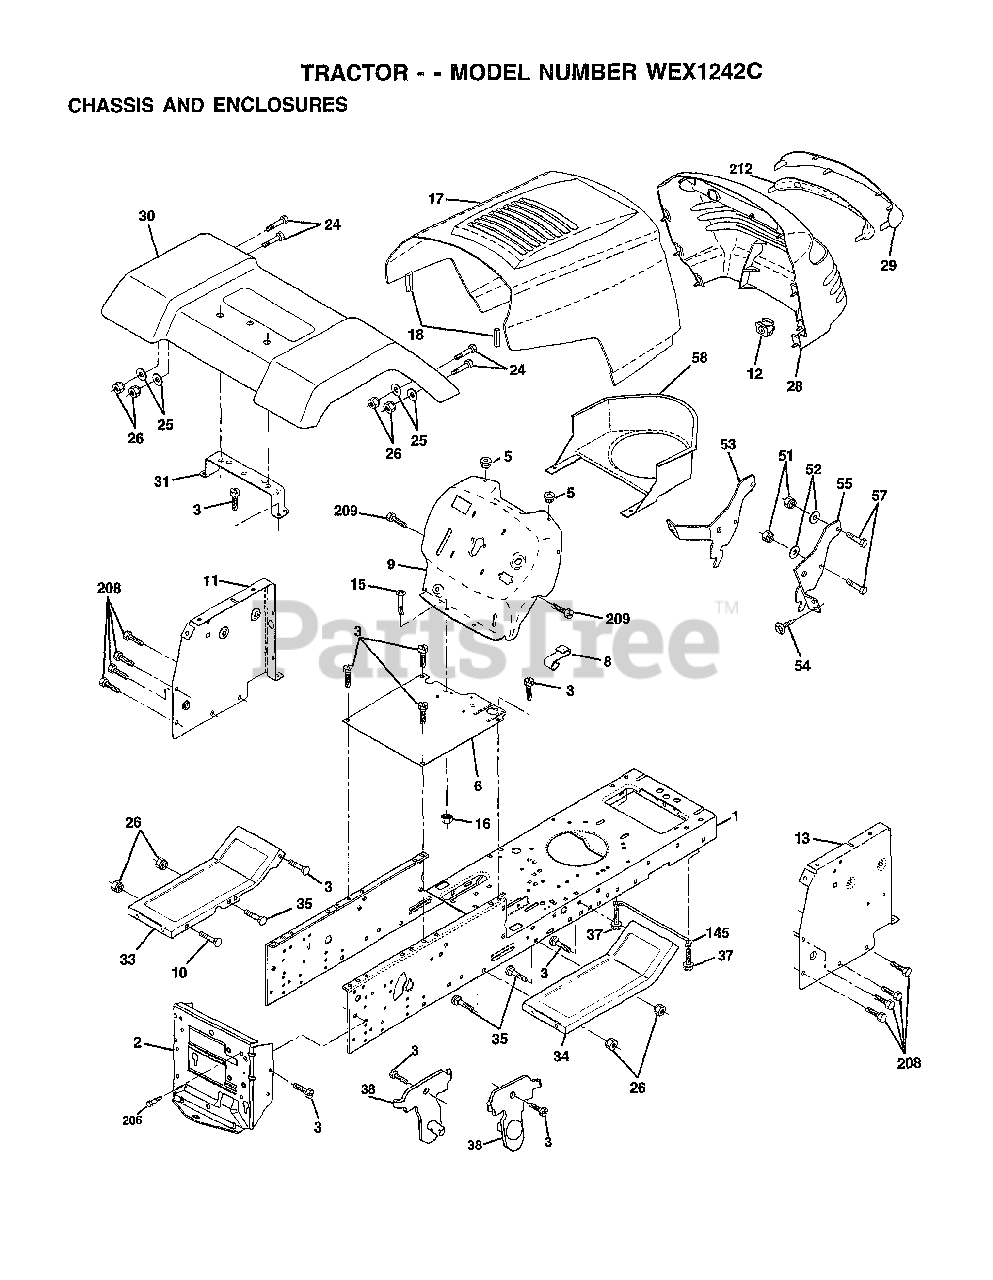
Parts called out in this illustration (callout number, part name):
2	DRAWBAR
3	SCREW
5	BUMPER-HOOD/DASH
6	SADDLE
8	CLIP.RETAINER
9	DASH
11	"PANEL-DASH,LH"
12	CLIP.TINNERMAN
15	SCREW
17	HOOD.STEEL.ASSY
24	BOLT
25	WASHER
26	NUT
28	GRILL.BLK
29	LENS.GRILLE.PRIVATE LABEL
30	FENDER
31	BRKT FENDER
33	FOOTREST.LH.PERF.
34	FOOTREST.RH.PERF.
35	BOLT
37	SCREW LT
38	BRKT ASM PIVOT MOWER REAR
52	WASHER
53	BRACKET.GRILLE.LH
54	SCREW.HEX.WS.HD
55	BRACKET.GRILLE.RH
58	AIR DUCT
145	"ROD POVOT,CHASSIS"
206	BOLT SHOULDER
208	SCREW
209	SCREW
212	INSERT LENS REFLECT
